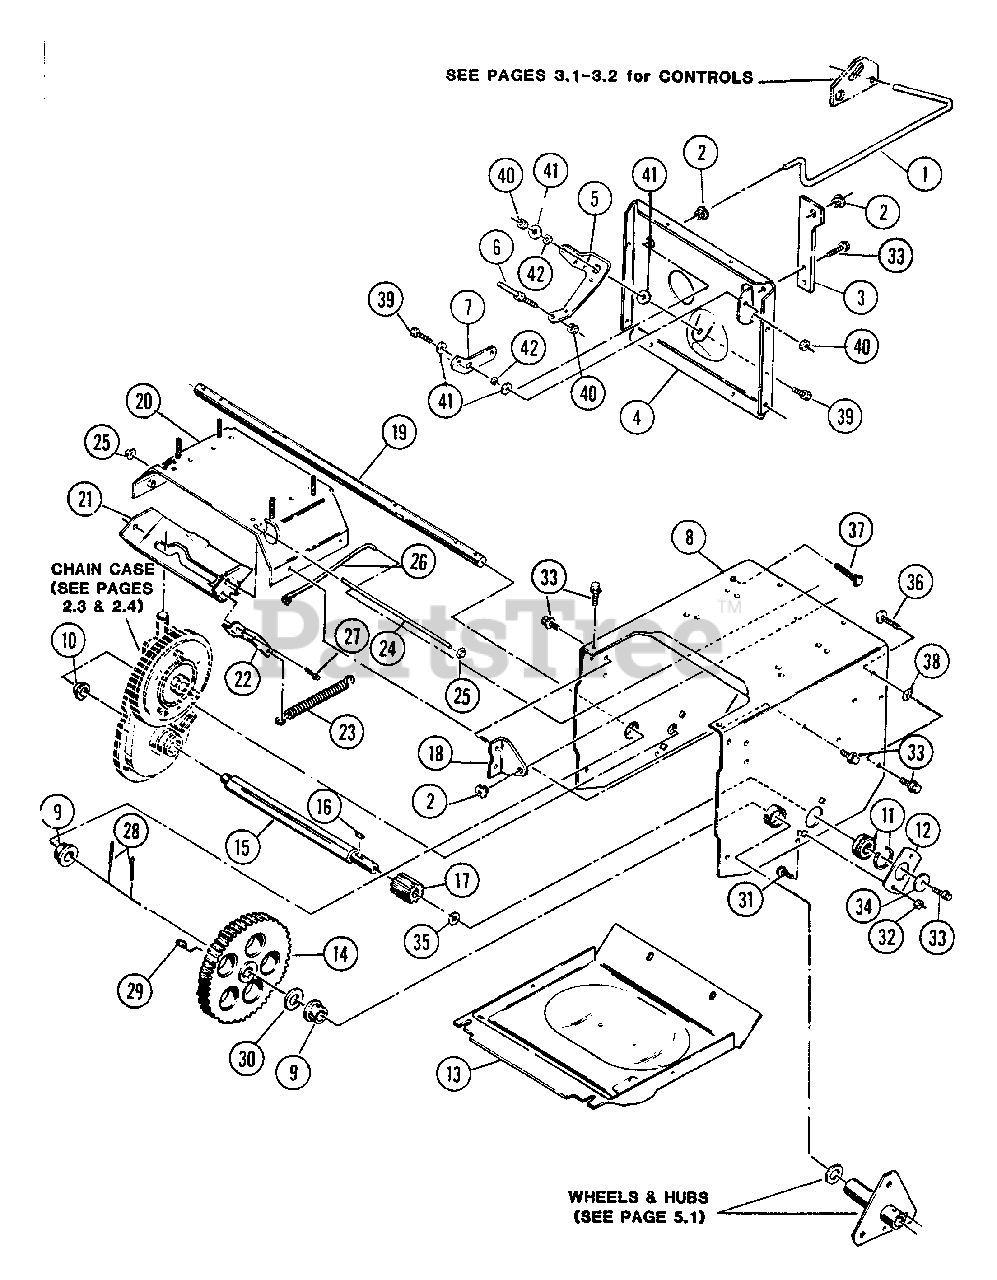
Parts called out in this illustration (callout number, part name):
1	ROD, Activating
2	BUSHING
3	BRACKET, Support
4	COVER, Frame Back
5	COVER, Frame Back
6	STUD, Shift Lever
7	BELL-CRANK, Traction
8	FRAME
9	BUSHING, Axle Shaft
10	BUSHING, Hex Shaft
11	BEARING
12	RETAINER, Bearing
13	COVER, Frame Bottom
14	GEAR, Axle Shaft
15	HEX-SHAFT
16	KEY, 1/8 x 5/8" Woodruff
17	PINION, Hex Shaft
18	BRACKET, Idler Mounting
19	AXLE-SHAFT
20	BRACE, Frame
21	BRACKET, Clutch
22	BRACKET, Spring
23	SPRING
24	CROSS-SHAFT
25	CAP, 5/16" Push
26	ROD, Push
27	SCREW, 1/4-20 x 3/8" Hex Washer Self-Tap
28	PIN, 3/16" x 1-1/4" Roll
29	KEY, 3/16 x 7/8" Woodruff
30	WASHER, 3/4 x 1-1/8" Flat
31	BOLT, 1/4-20 x 1/2" Short Neck Carriage, Grade 5
32	NUT, 1/4-20 Hex Flange Lock
33	SCREW, 5/16-18 x 5/8" Hex Washer Self-Tap
34	WASHER, 3/8 SAE
35	WASHER, Shim
36	BOLT, 5/16-18 x 3/4" Square Neck Carriage, Grade 5
37	BOLT, 5/16-18 x 1-3/8" Short Neck Carriage, Grade 5
38	RETAINER, 5/16" Bolt
39	SCREW, 5/16-18 x 3/4" Hex Head Cap, Grade 2
40	NUT, 5/16-18 Hex Center Lock
41	WASHER, 5/16" x 1-1/4" x 3/32" Flat
42	SPACER
